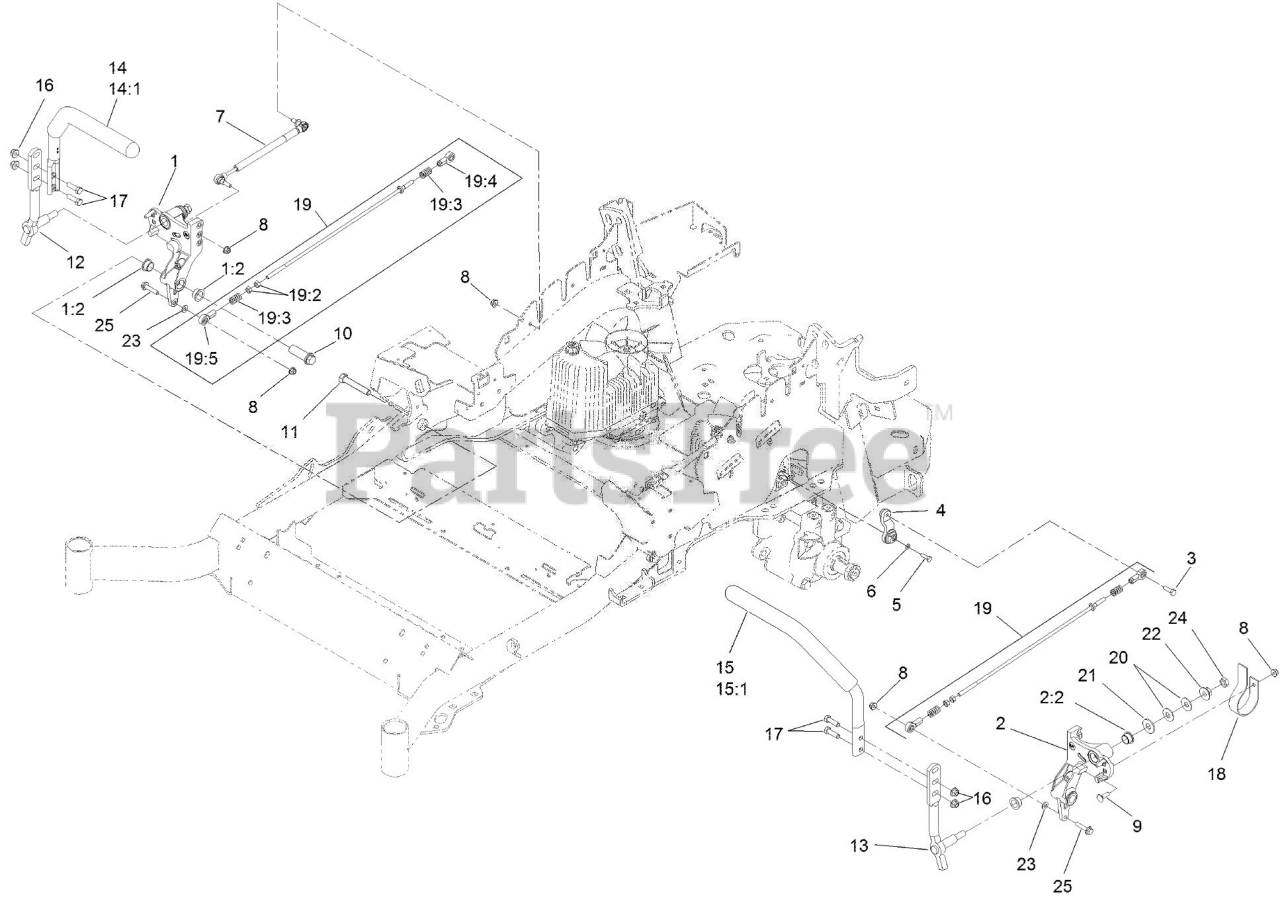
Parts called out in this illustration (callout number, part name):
1	RH MOTION CONTROL AND BUSHING ASM
1:2	BUSHING-FLANGE
2	LH MOTION CONTROL AND BUSHING ASM
2:2	BUSHING-FLANGE
3	SCREW-HH, THREAD LOCKING
4	ARM-CONTROL, PUMP
5	SCREW-HH
6	WASHER-SPRING
7	DAMPER-CONTROL, MOTION
8	NUT-HF, NI
9	BOLT-CARR
10	HUB-THREADED
11	SCREW-HH
12	LEVER-CONTROL MOTION, RH
13	LEVER-CONTROL MOTION, LH
14	RH STEERING HANDLE ASM
14:1	GRIP-LEVER, CONTROL
15	LH STEERING HANDLE ASM
15:1	GRIP-LEVER, CONTROL
16	NUT-HF, NI
17	SCREW-HH
18	SPRING-LEAF
19	PUMP LINKAGE REAR ASM
19:2	NUT-HEX
19:3	SPRING-COMPRESSION
19:4	BALLJOINT-LH
19:5	BALLJOINT-RH
20	WASHER-SPRING
21	WASHER-FLAT
23	WASHER-PLAIN
24	NUT-JAM
25	SCREW-HHF
